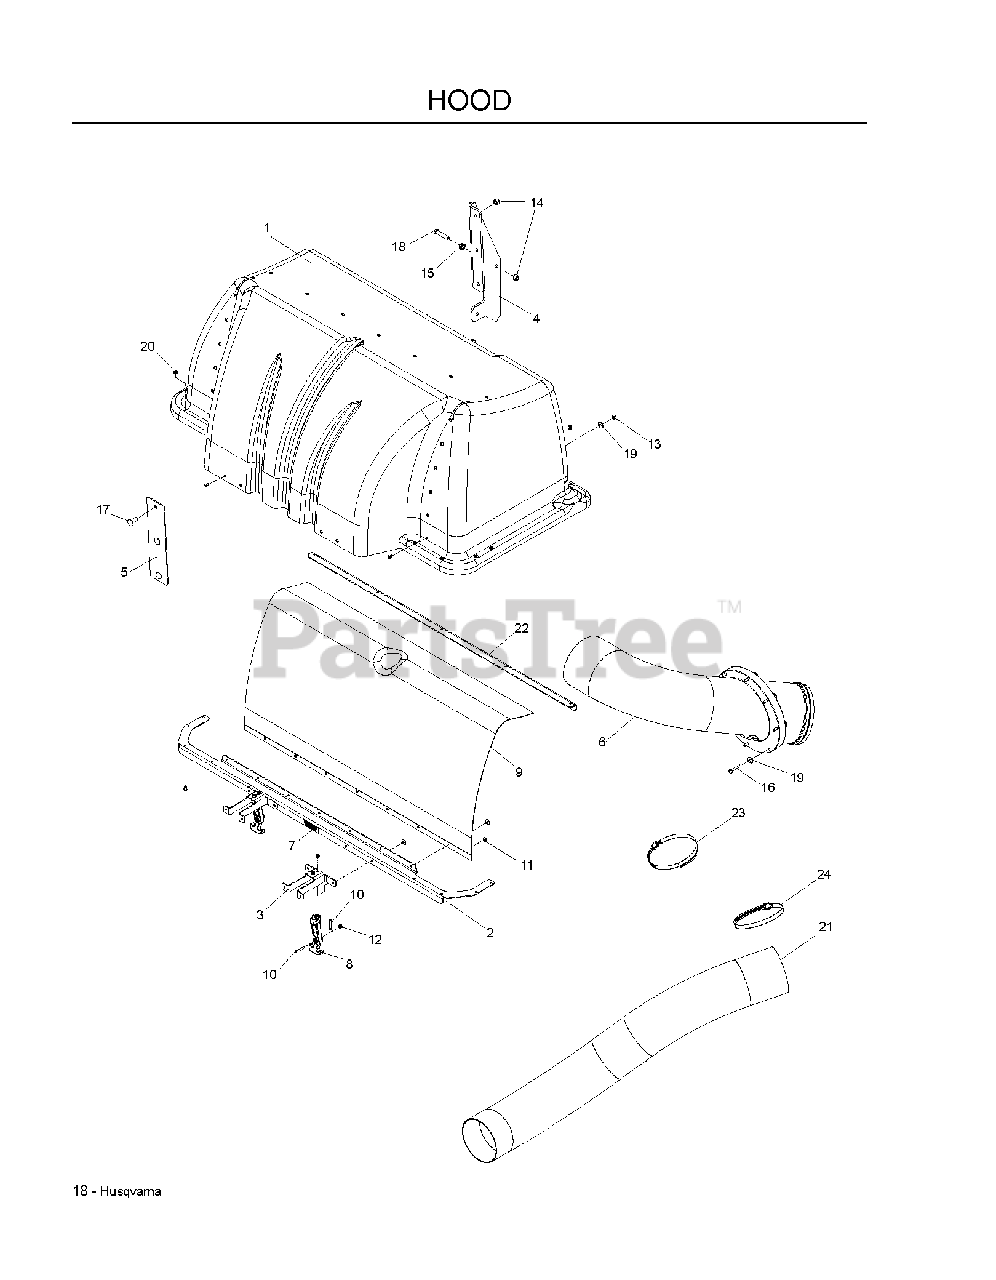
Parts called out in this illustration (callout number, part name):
2	HOOD SUPPORT
3	SUPPORT, DRAW LATCH
4	HOOD HINGE
5	MOUNT PLATE
6	INLET TUB
7	DECAL, VENTILATION
9	MESH, POLY DIAMOND
10	SCR, #10-24 X 1-1/8
11	WASHER #10
12	NUT 10-24 NYLOC
13	NUT 1/4-20 NYLOC
14	NUT 3/8-16 NYLOC
15	NUT 3/8C WHIZ
16	BOLT 1/4C X 1 3/4
17	RHSNB 3/8C X 1
18	HCS 3/8CX 1 3/4
19	WASHER 1/4 FLAT
20	WASHER, #10 MACH SCR BLK OX
21	HOSE, 7" X 42"
22	HOOD SUPPORT, REAR
23	OVER CTR BAND
24	HOSE CLAMP 4-3/4 TO 7-3/4"
